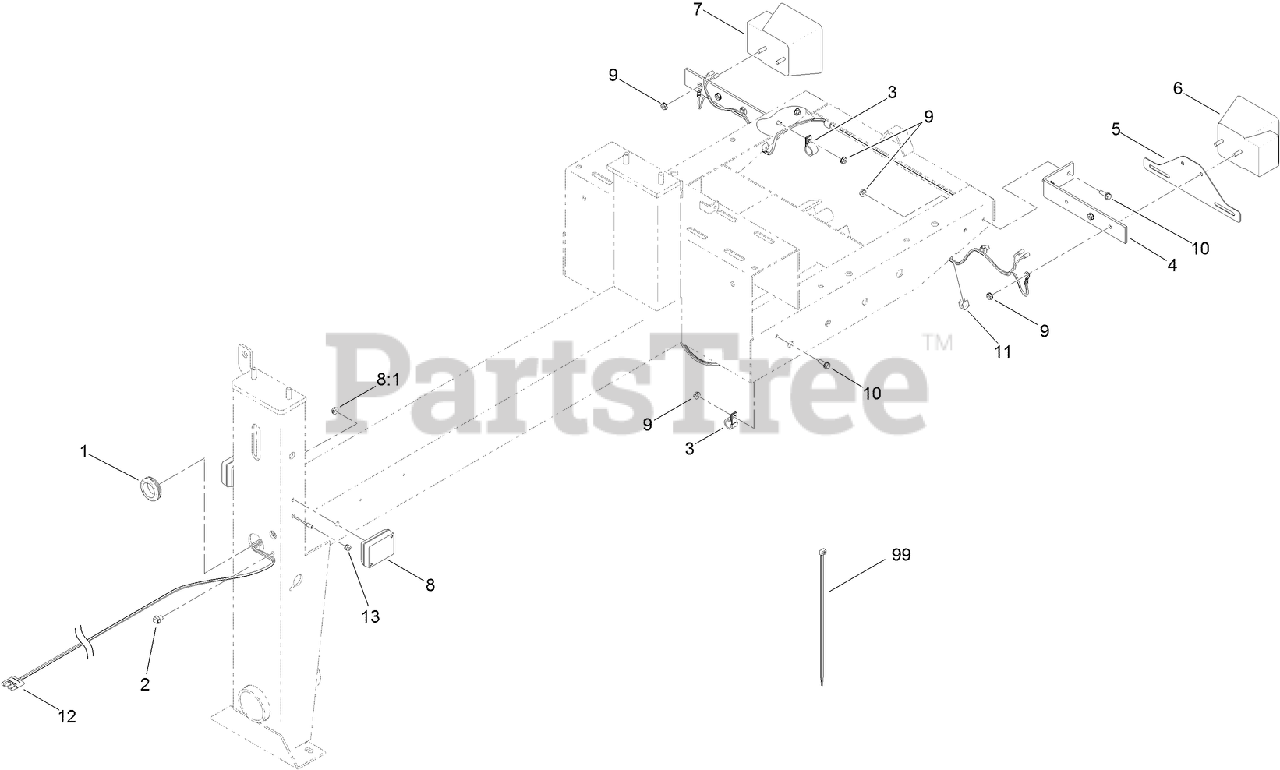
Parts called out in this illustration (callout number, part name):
1	GROMMET
2	CLIP-TIE
3	CLAMP-CABLE
4	BRACKET-UNIVERSAL
5	HOLDER-PLATE, LICENSE
6	LIGHT-TAIL, LH
7	LIGHT-TAIL, RH
8	LAMP-MARKER, FRONT SIDE
8:1	NUT-KEPS
9	NUT-KEPS
10	SCREW-HHF
11	CLIP-EDGE
12	HARNESS-WIRE
13	GROMMET
99	TIE-CABLE
